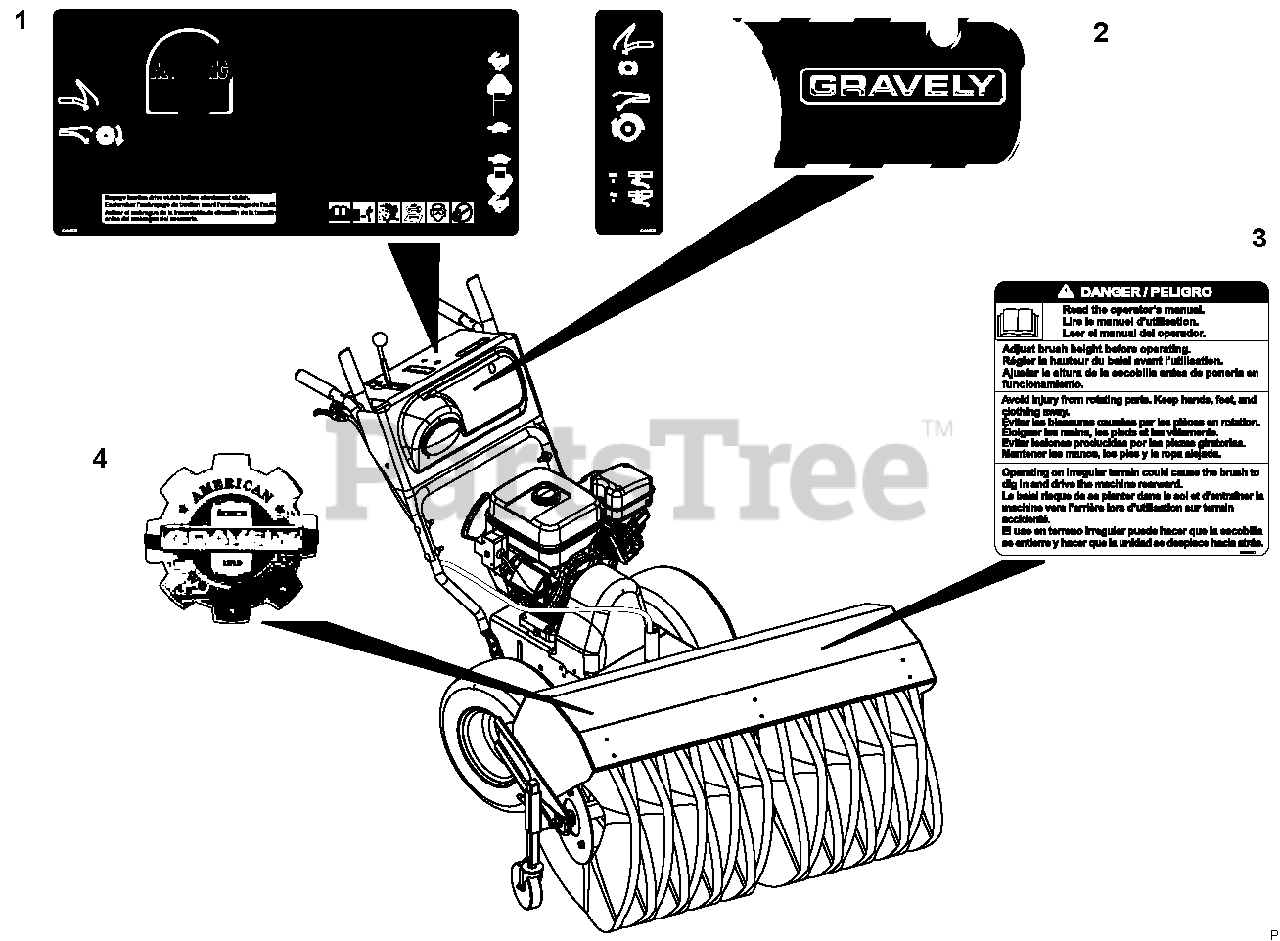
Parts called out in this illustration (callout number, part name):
1	Decal, Control Brush
2	Decal, Front Dash Brush
3	Decal, Caution
4	Decal, Gravely Heritage
